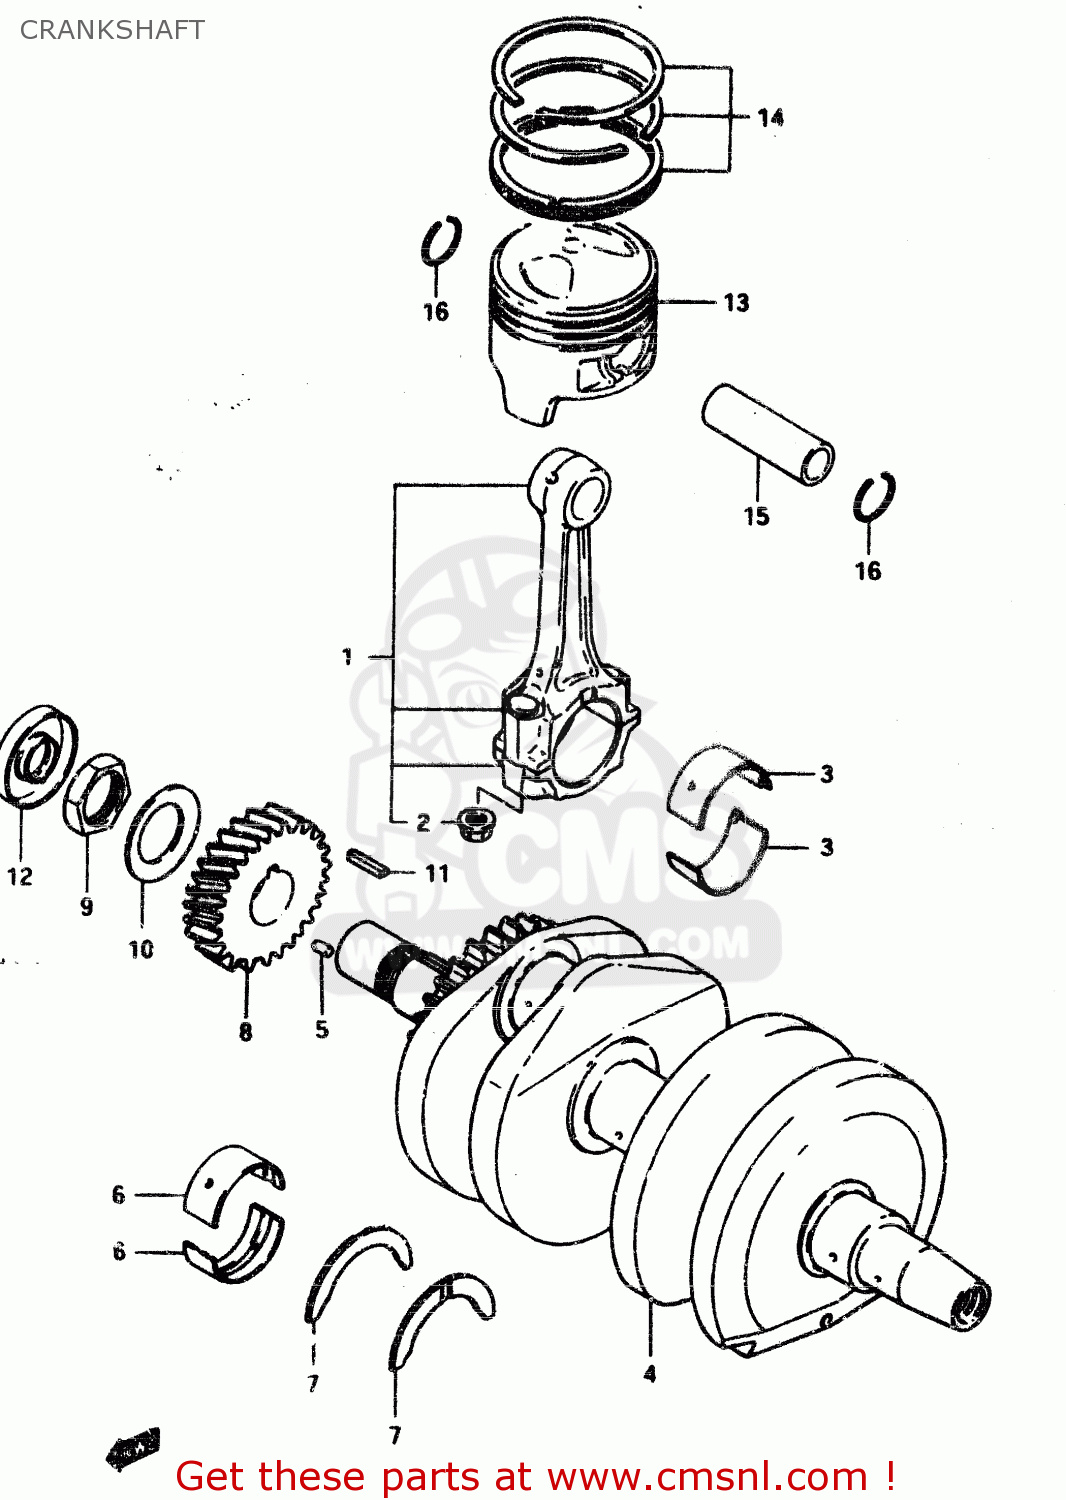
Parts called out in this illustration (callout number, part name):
1	ROD ASSEMBLY,CONNECTING
2	NUT
3	BEARING,CRANK PIN
4	CRANKSHAFT
5	PIN 3X5
6	METAL CRANKSHAFT
7	BEARING,CRANK THRUST
8	GEAR,PRIMARY DRIVE NO.28
9	NUT
10	WASHER
11	KEY
12	OIL SEAL
13	PISTON
14	RING SET,PISTON
15	PIN,PISTON (18MM)
16	CIRCLIP,PISTON PIN
